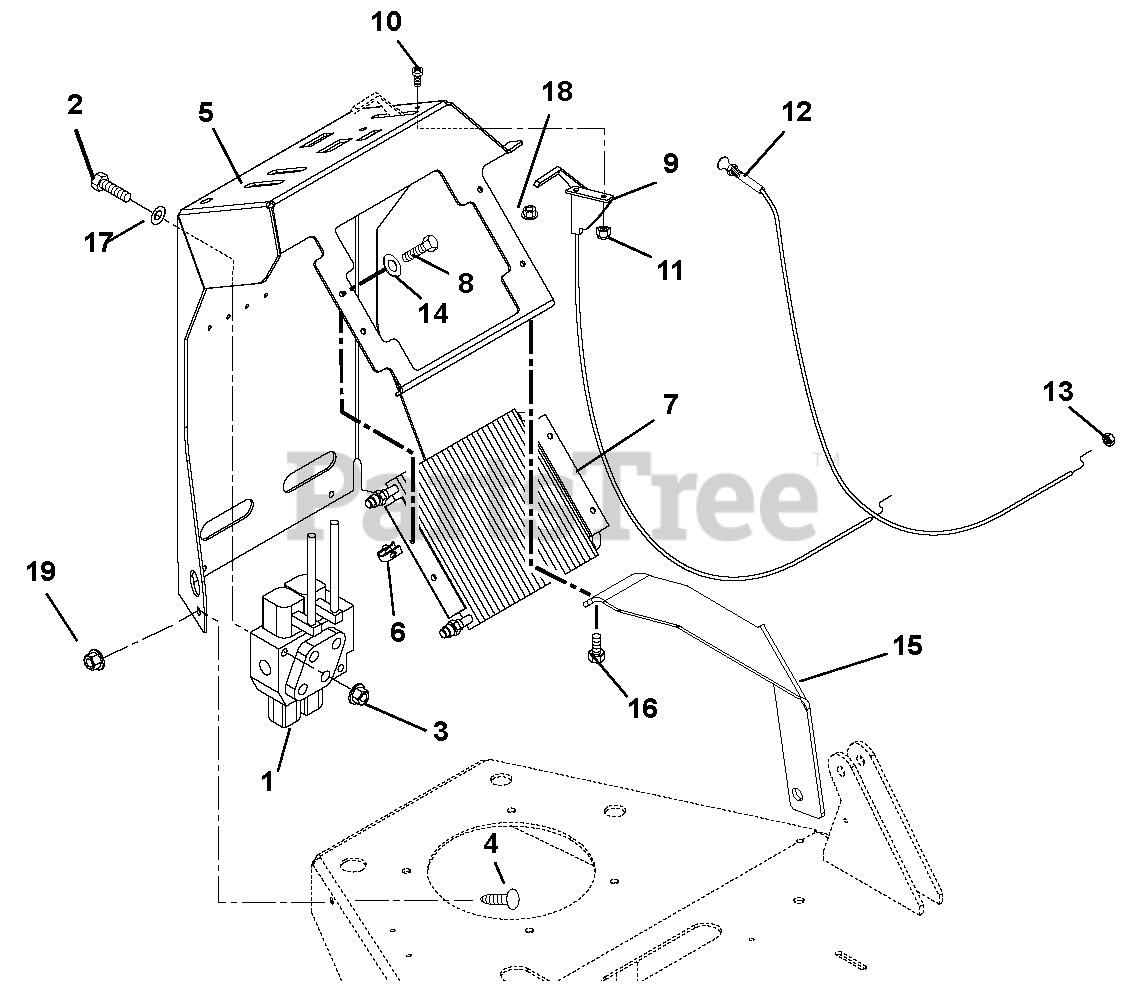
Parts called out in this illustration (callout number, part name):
1	Valve, 2 Spool
2	Bolt, Hex .31-18 x 1.75 Grade 5
3	Nut, Locking-Top-Flange .31-18
4	Bolt, Round Head Square Neck .38-16 x .75 Grade 5 YWZC
5	Panel, Control
6	Nut, Retainer .25-20 x .56
7	Cooler, Oil
8	Bolt, Hex .25-20 x .75 Grade 5
9	Cable, Control
10	Screw, Machine 10-24 x .50 Hex Washer Head
11	Nut, Locking-Nylon 10-24 with Insert
12	Cable, Choke
13	Nut, Jam .38-24
14	Washer, Flat-Steel .28 x .62 x .065
15	Brace, Instrument Panel-Left Hand
16	Bolt, Hex .25-20 x .75 Grade 5
17	Washer, Flat-Steel .344 x .688 x .065
18	Nut, Locking-Top-Flange .25-20
19	Nut, Lock Top Flange .38-16 YWZC
